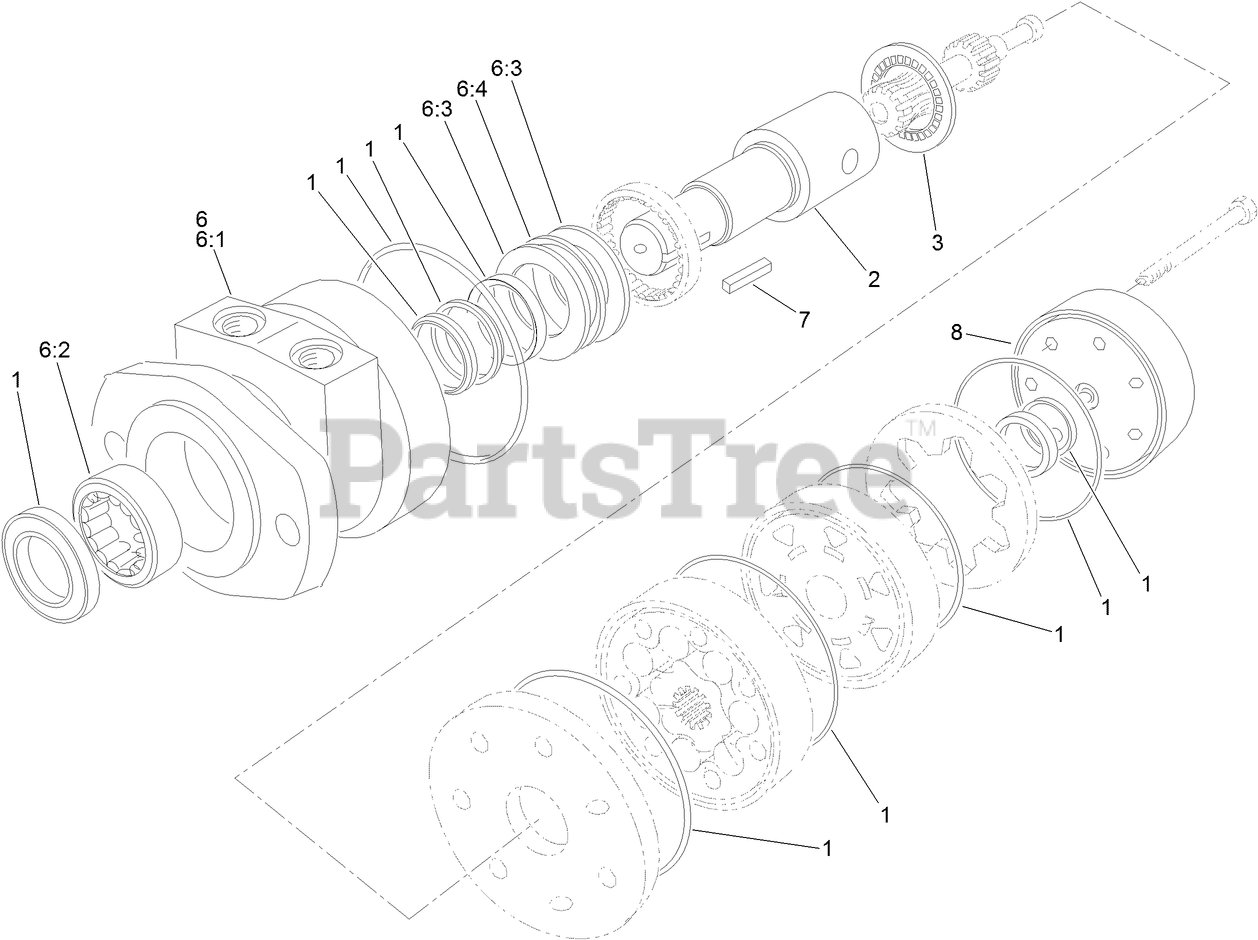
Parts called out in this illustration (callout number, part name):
2	COUPLING SHAFT
3	BEARING-THRUST
6	HOUSING ASM
6:1	HOUSING
6:2	Bearing
6:3	HUB and BEARING ASM
6:4	HUB and BEARING ASM
7	KEY-SQUARE
8	END COVER ASM
